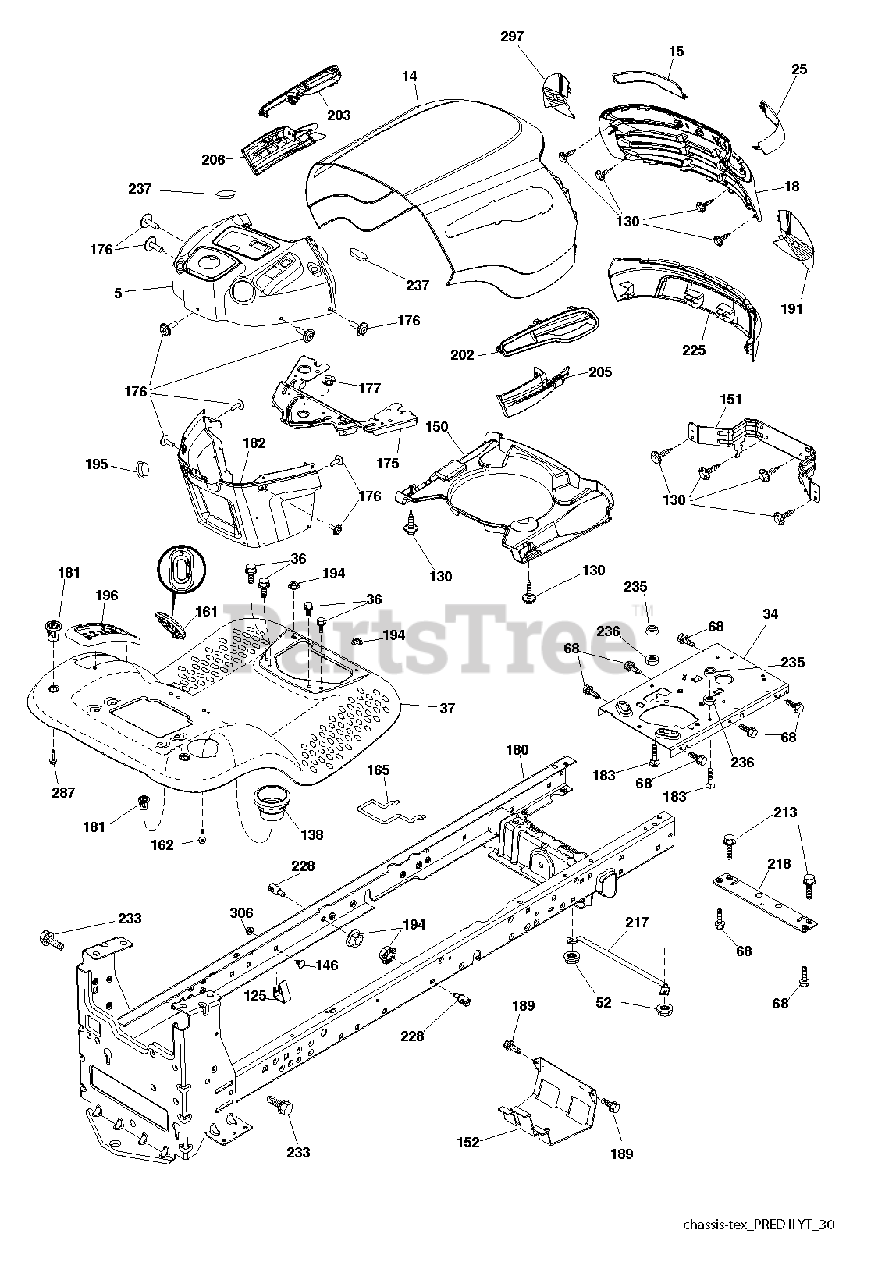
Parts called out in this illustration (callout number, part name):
36	SCREW 5/16"
52	LOCKNUT
125	Fuel Line Clip
130	SCREW.#10 X 0.750.BOS THREAD
138	CUPHOLDER.TL.TEX.BLACK
146	BOLT.RDHD.SHT.SQNK.3
150	PREDATOR.YT.GT.HOOD.A
152	SHIELD BROWNING
161	WINDOW.FUEL.LT.TEX.BLACK
162	SCREW.HI-LO.CONSOLE
165	SUPPORT.TANK.REAR.W/TE
175	PLATE.CROSSMEMBER.HUSQ
176	SCREW.#10-24X5/8.RN.QU
177	BUSHING STEERING
180	CHASSIS
181	BUSHING.MNT.FEND.CRGO.TEX.49
182	DASH.LOWER.COMMON.12V.ADAPTOR
183	BOLT.5/16-18X1-1/4 FULL THD
189	SCREW
194	NUT LOCK HEX FLANGE 5/16-18
195	PLUG.HOLE.DASH.LOWER.12V.BLK
196	CONSOLE.ASM.DECKLFT.BL/RBT.TLT
202	VENT.SIDE.RH.PRED2.GTYT.JONS
203	VENT.SIDE.LH.PRED2.GTYT.JONS
205	TRIM.SIDE.YT48/PRED2.RH.BL
206	TRIM.SIDE.YT48/PRED2.LH.BL
213	BOLT
217	ROD.PIVOT.HOOD
218	X-PIECE.HOOD.STOP.NON/
228	STUD.FASTNER.W/ANTI-ROTATE
233	BOLT.SHOULDER
235	SPACER FENDER
236	NUT.CENTERLOCK.5/16-
237	PLUG.MOUNT.CARGO.BLK
306	NUT LOCK FLG 3/8-16 UNC
